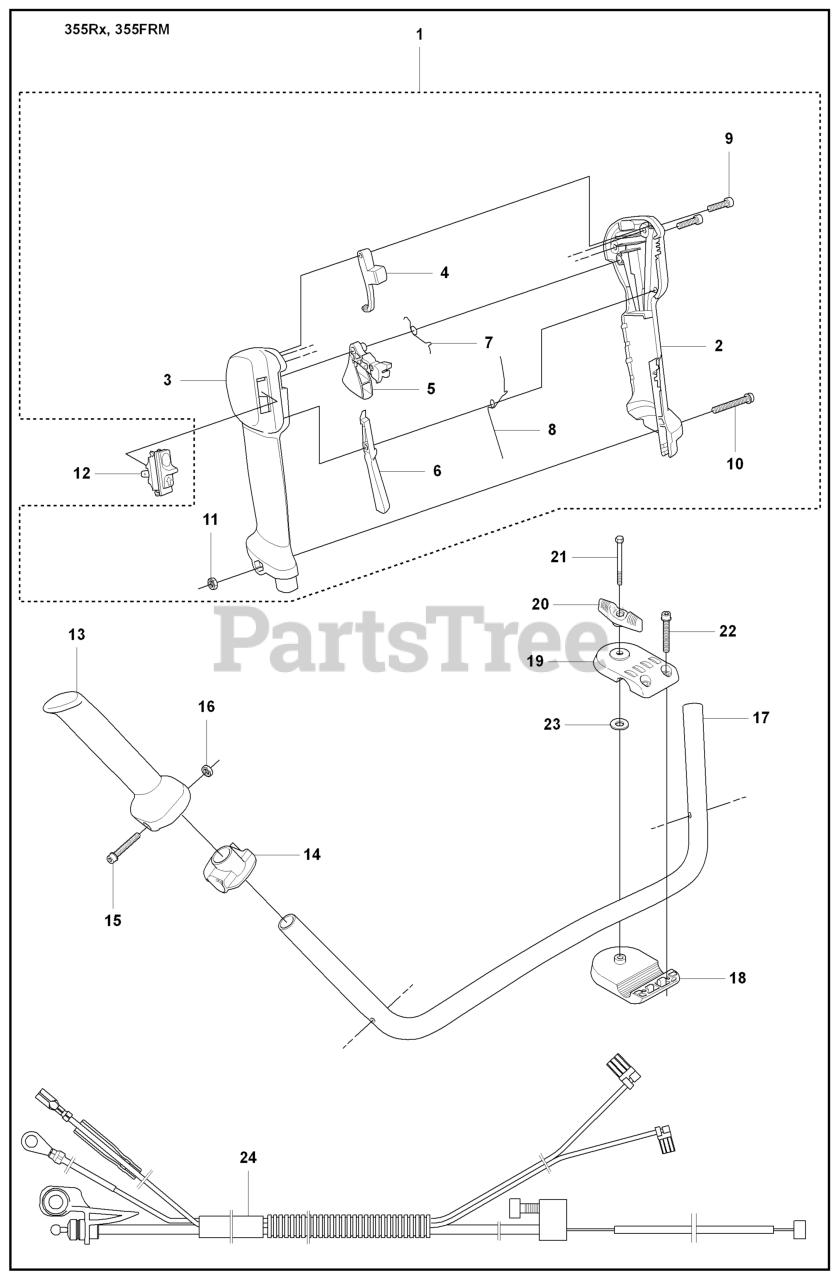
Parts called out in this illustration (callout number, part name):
1	THROTTLE HANDLE ASSY
2	HANDLE HALF RIGHT
3	HANDLE HALF LEFT
4	LOCKOUT STARTER THROTTLE
5	THROTTLE TRIGGER
6	THROTTLE LOCK
10	SCREW
12	STOP BUTTON
16	NUT M6M M5
17	HANDLE
18	HANDLE HOLDER LOWER
19	HANDLE HOLDER UPPER
21	%SCREW
24	WIRING
